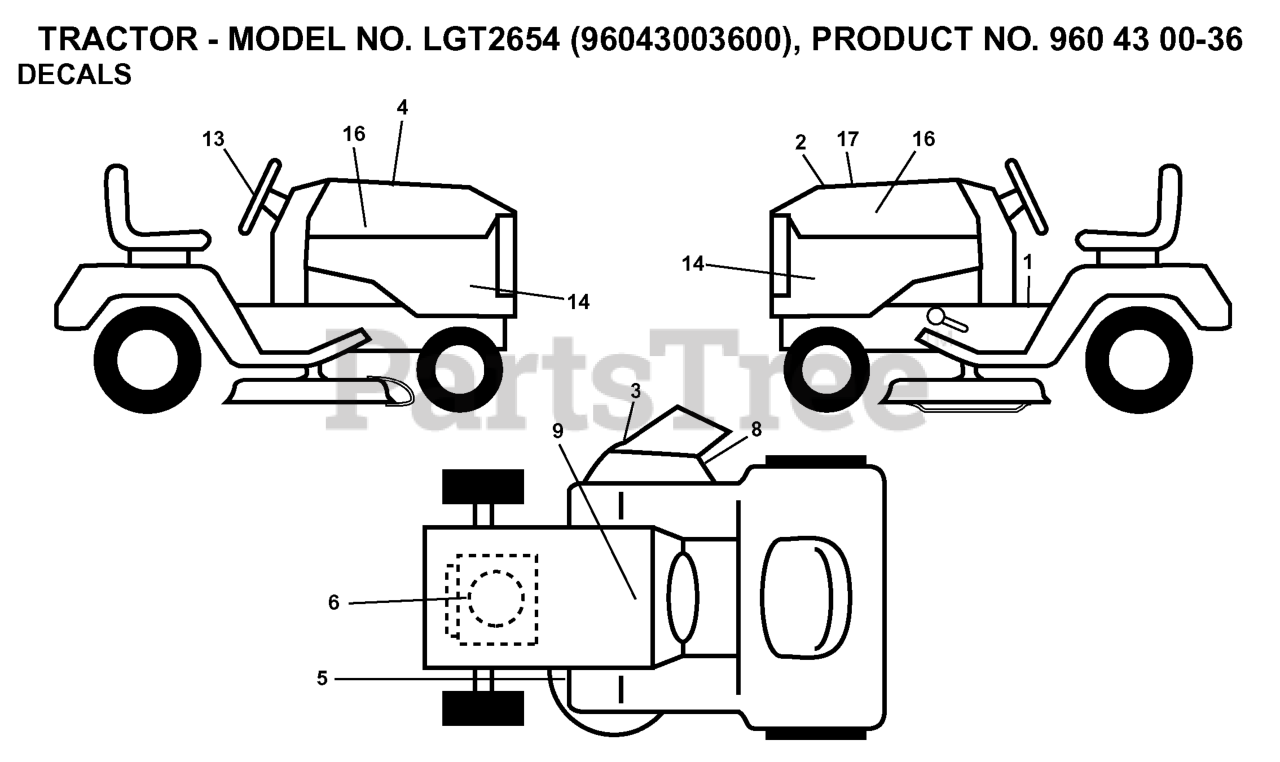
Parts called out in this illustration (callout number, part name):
1	DECAL.FENDER.OPER.TEX.
2	DECAL.HOOD.TOP.INSERT.
3	DECAL.WARN.KEEP.HAND.AWAY
4	DECAL HOOD CUST. RESP.
5	DECAL CLUTCH/BRAKE
6	DECAL, ENG. HP
8	DECAL.MOWER.SCH.48/54
9	DECAL BTRY SYMBOLS
13	DECAL.WHEEL.STRG.LGN.H
14	DECAL, PANEL SIDE
16	DECAL.HOOD.NAMELOGO.HUSQ
